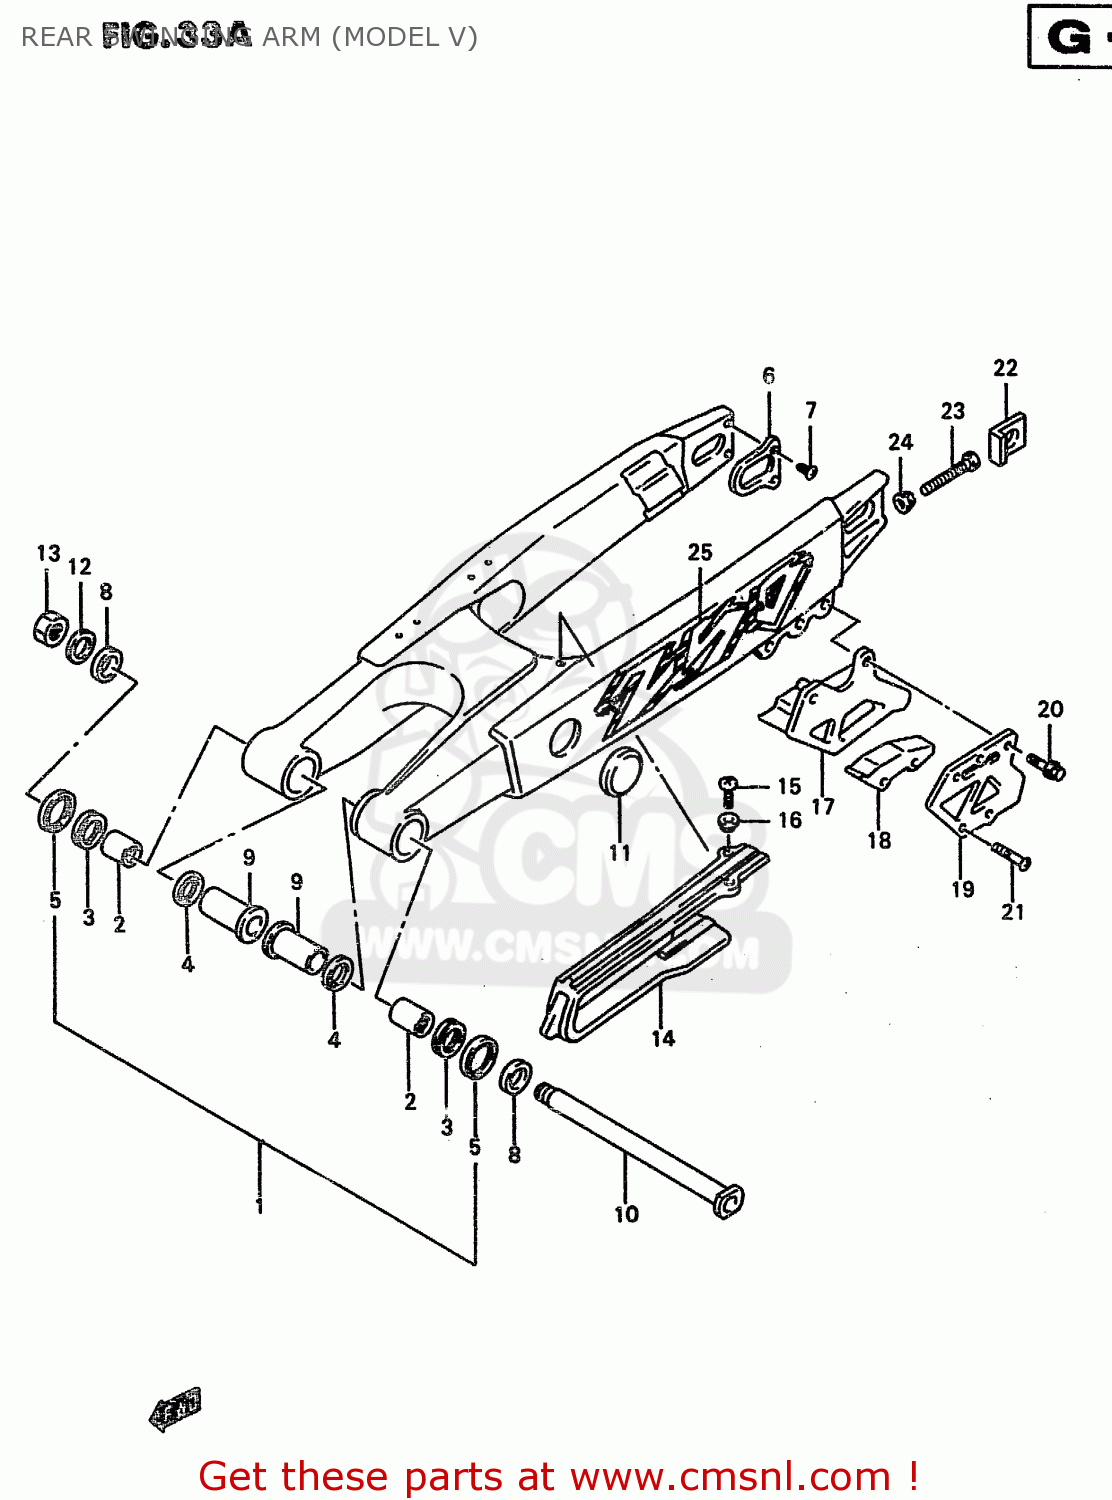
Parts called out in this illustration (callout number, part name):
1	SWING ARM ASSEMBLY,REAR
2	BEARING(22X29X30)
3	BEARING(22X35X2)
4	SEAL,OIL(22X29X4)
5	SEAL,RR SWGARM PIVOT OUTER
6	PLATE,SWING ARM,REAR
7	SCREW(5X8)
8	SPACER,RR SWGARM PIVOT OUTER
9	SPACER,SWGARM PIVOT INNER
10	SHAFT,RR SWINGINGARM PIVOT
11	CAP(OD:45)
12	WASHER, FIXED DRIVE FACE
13	NUT
14	BUFFER,CHAIN TOUCH DEFENSE
15	SCREW
16	WASHER
17	GUIDE,CHAIN
18	DEFENSE,CHAIN GUIDE
19	PLATE,CHAIN GUIDE OUTER
20	SCREW
21	SCREW(6X40)
22	WASHER,CHAIN ADJUSTER
23	BOLT(8X50)
24	NUT
25	EMBLEM,SWING ARM
